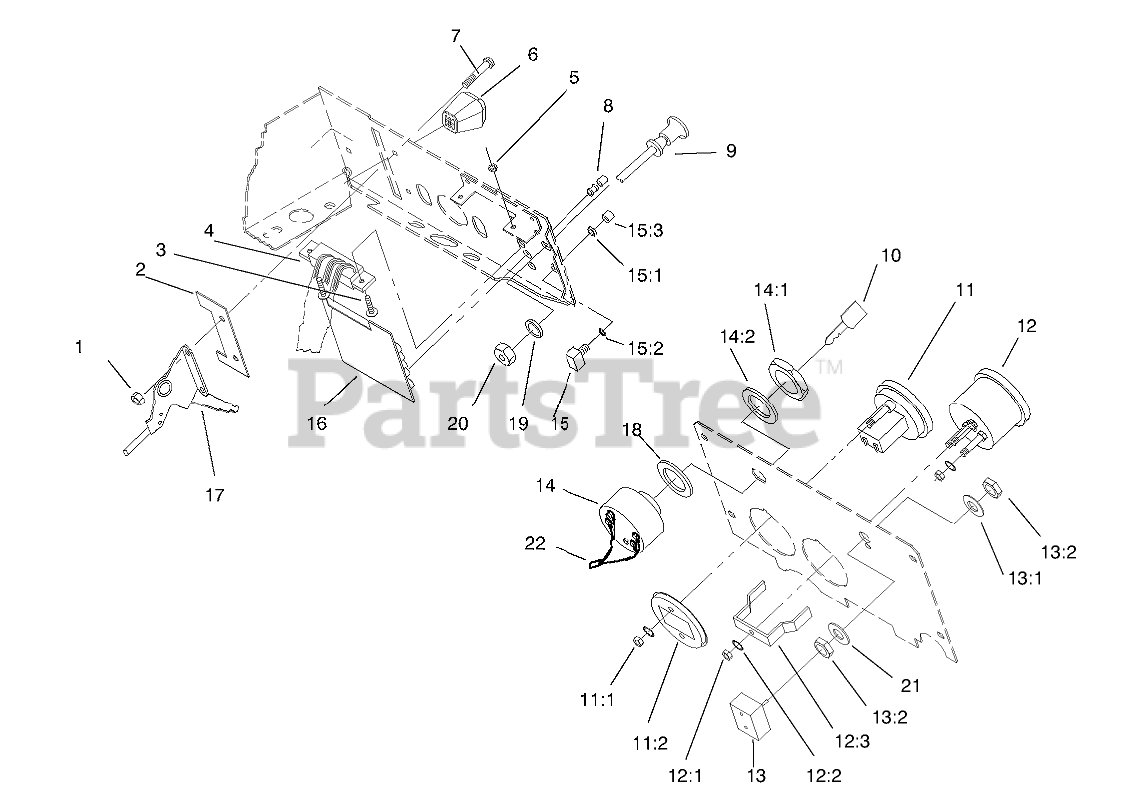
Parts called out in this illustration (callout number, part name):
1	Nut
2	STOP-THROTTLE
3	Screw
4	P.C. BOARD HARNESS
5	NUT-HEX
7	SCRW-PHC
8	ASSY LENS & BUSHING
9	CONTROL-CHOKE
10	KEY-IGNITION
11	Hourmeter
11:1	NUT-HEX, KEPS
11:2	Retainer
12	VOLTMETER
12:1	NUT-HEX
12:2	WASHER-LOCK
12:3	CLAMP-MOUNTING
13	SWITCH-LIGHTS
13:1	TAB-WASHER
14	IGNITION SWITCH ASM
14:2	WASHER-LOCK
15	SWITCH-PUSH BUTTON
15:1	NUT F/W 116796
15:2	Washer
15:3	BUTTON F/W 116796
16	Board-Pc
17	CONTROL-THROTTLE
18	WASHER
19	WASHER-FLAT
20	NUT-HEX PALNUT
21	WASHER
22	WIRING-HARNESS & DIA
